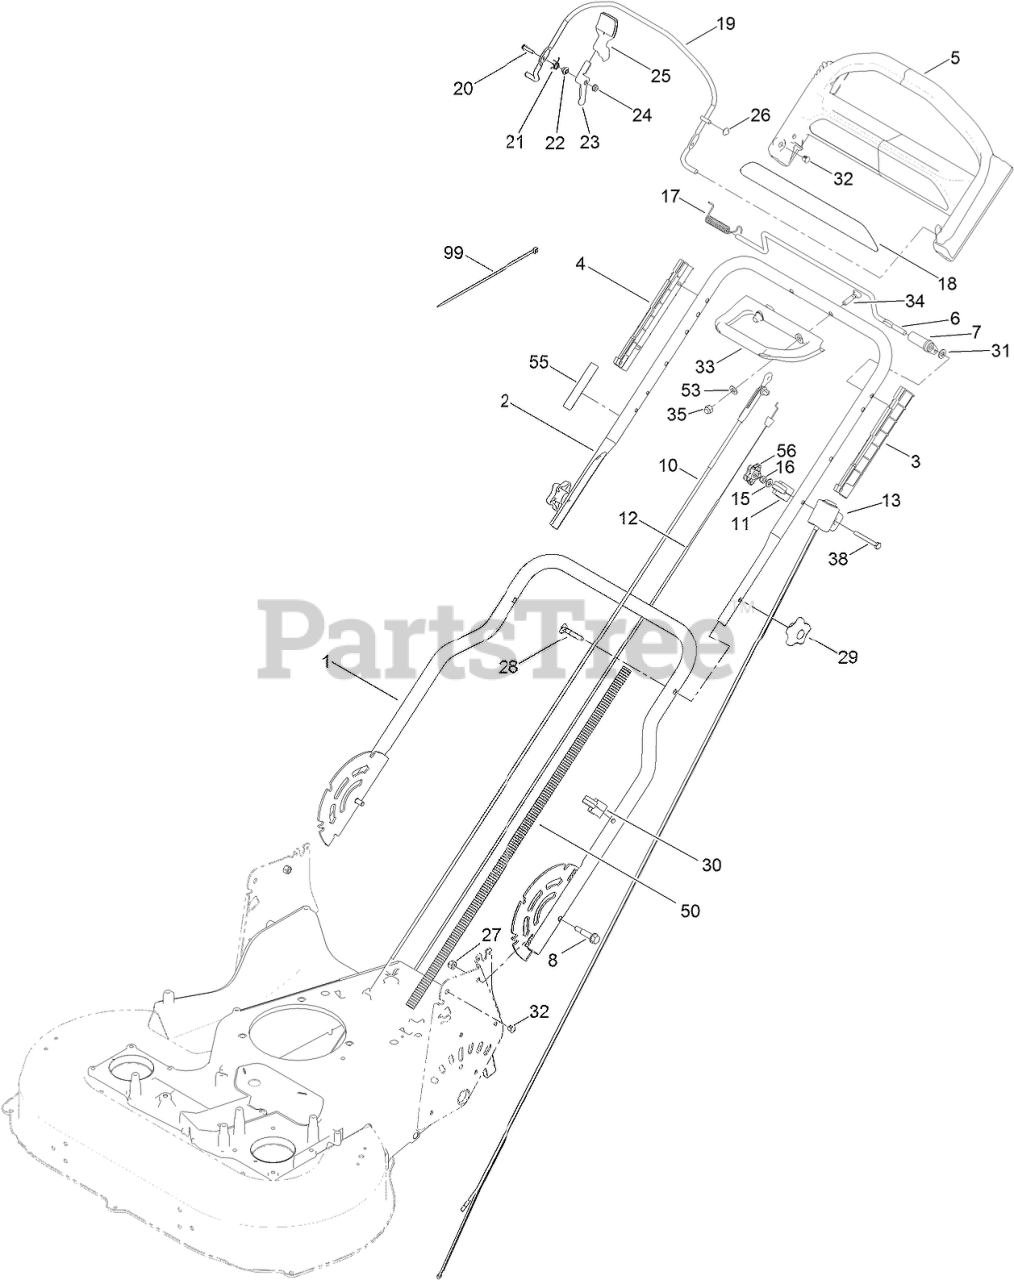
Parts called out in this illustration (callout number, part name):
1	HANDLE-LOWER
2	HANDLE-UPPER
3	GUIDE-LH
4	GUIDE-RH
5	HANDLE-CONTROL
6	BAR-CONTROL, TRACTION
7	LEVER-TRACTION
8	BOLT-SHOULDER, HHF
10	CABLE-BRAKE, BBC
11	ANCHOR-CABLE
12	CABLE-TRACTION
13	SWITCH HOUSING ASM
15	WASHER-FLAT
16	NUT-LOCK, NI
17	Spring-Torsion
18	DECAL-HANDLE
19	BAIL-BRAKE
20	SCREW-HWH
21	SPRING-TORSION
22	SPACER
23	LEVER
24	NUT-LOCK, FLANGE
26	NUT-SPEED
27	NUT-LOCK, NI
28	SCREW-HANDLE
29	KNOB-HANDLE
30	GUIDE-CABLE
31	SPACER
32	Plug-Dome
33	HANDLE-ASSIST, TRACTION
34	SCREW-HANDLE, LOCK
35	NUT-ACORN
38	SCREW-HH
50	CONDUIT-CONVOLUTED
53	WASHER-PLAIN
55	DECAL-TRACTION, ADJUST
56	KNOB-HANDLE, LOCKING
99	TIE-CABLE
